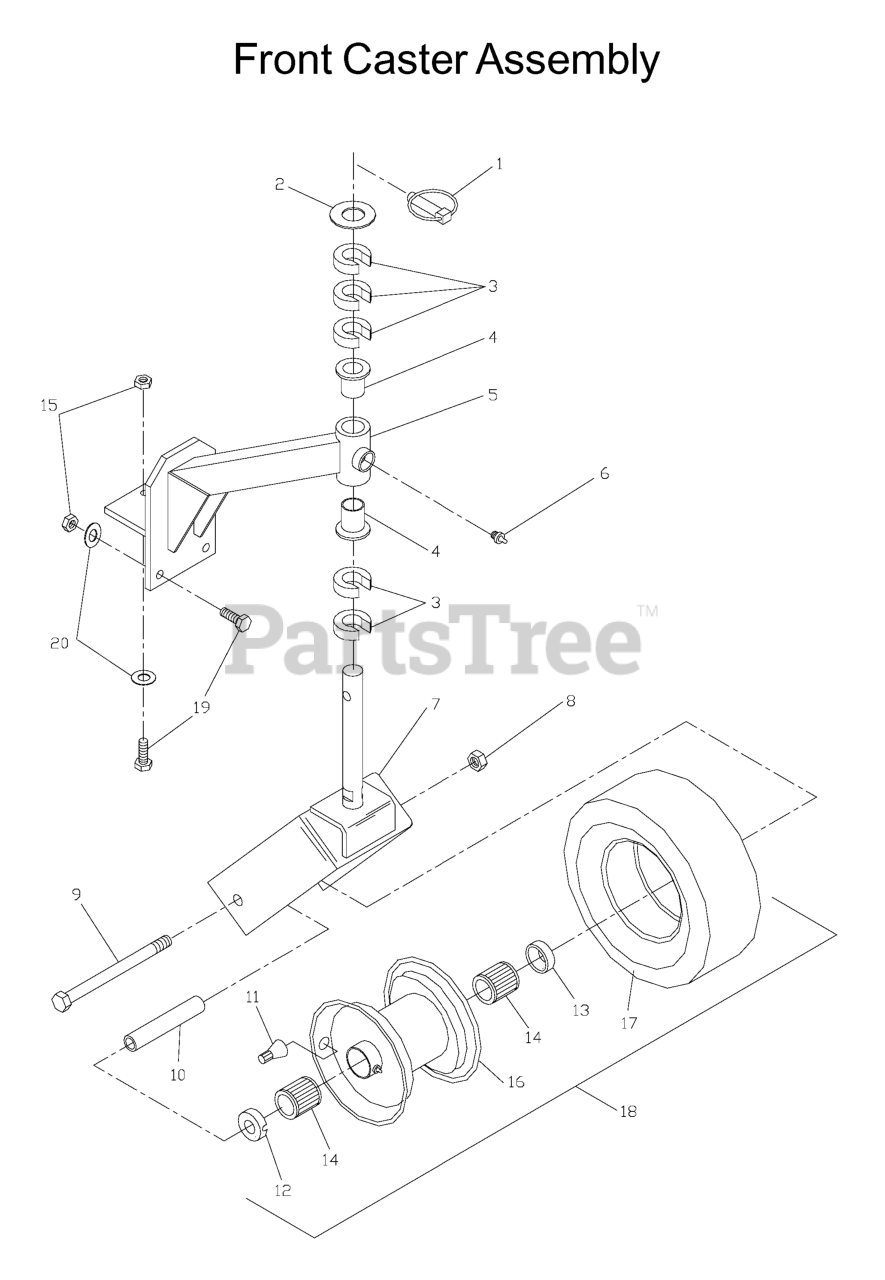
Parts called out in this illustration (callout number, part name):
1	LYNCH PIN 7/16
2	MACHINE BUSHING
4	BUSHING, FLANGED
5	CASTER ARM W/BUSHING
6	ZERK 1/8 NPT
7	CASTER YOKE
8	NUT 1/2-13 HEX NYLOC ZD
9	HCS 1/2C X 5 1/2
11	VALVE STEM TR-412
12	ENDCAP, NOTCHED
13	ENDCAP
14	ROLLER BEARING
15	NUT 3/8C CENTERBLOCK
17	TIRE 9 X 3.5 - 4
18	TIRE/WHEEL.CASTER.9X3.5-4.SMOO
19	HCS 3/8-16X1.GRD.5.ZD
20	WASHER 3/8 FLAT
21	WHEEL CAST. ASM KIT
